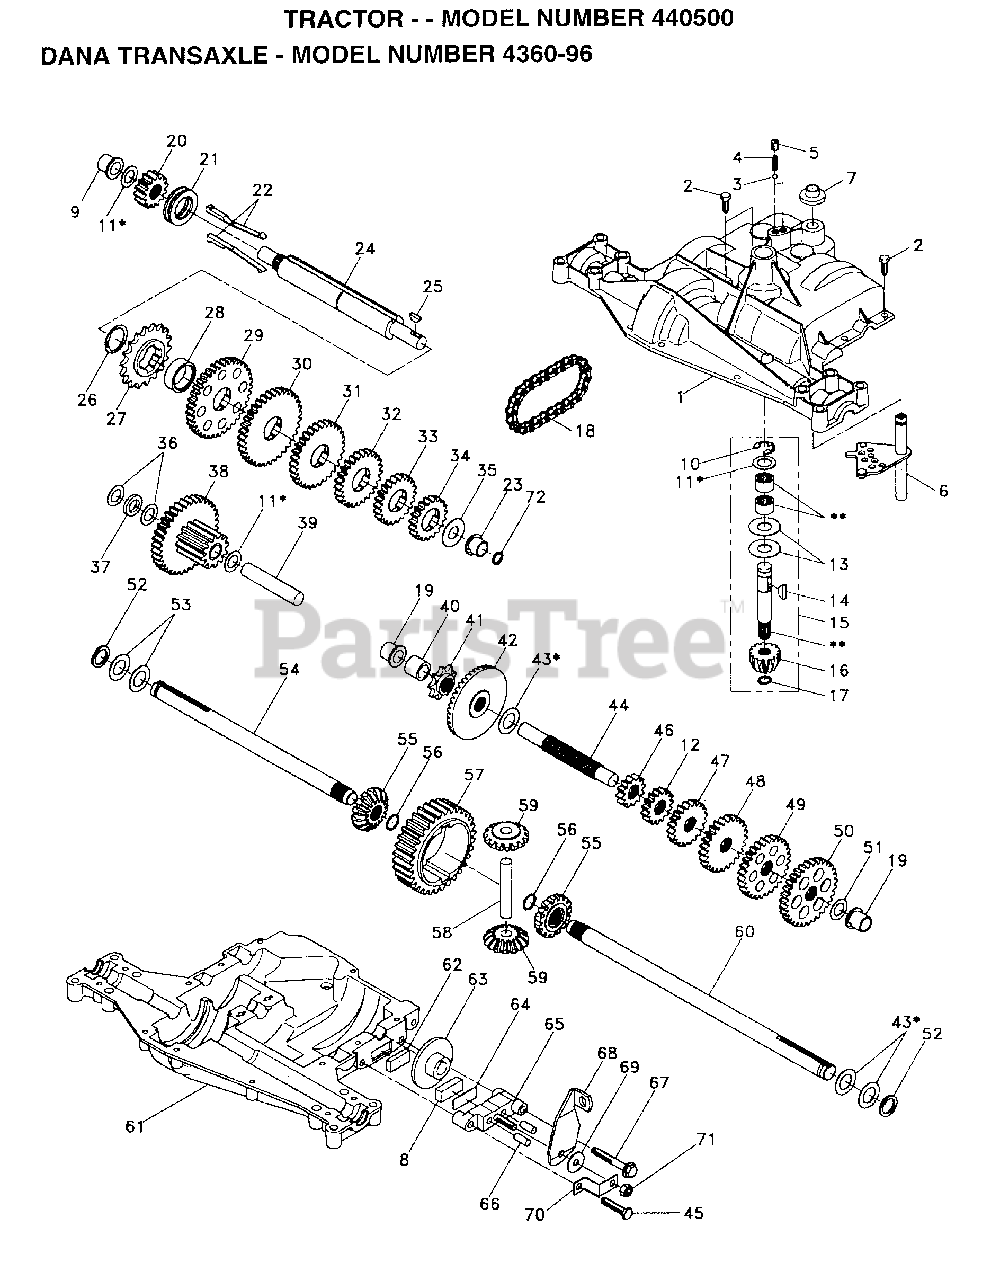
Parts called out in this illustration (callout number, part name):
1	HARNESS.IGNITION
4	"SPRING, DETENT LT"
5	"SCREW, SET LT"
6	KIT SHIFTER ASM
7	SHIFTER BOOT
8	PUCK T
10	RETAINING RING LT
11	ASM KIT SHIM 4689
12	PLUG.PLASTIC
13	WASHER T
14	KEY WOODRUFF-DANA
17	"RING,RETAINING LT"
18	"CHAIN,24 PTCH LT"
19	BEARING.FLNG.5510
20	GEAR SPUR 14 TTH
21	CLUTCH.COL.5467
22	KIT.ASM.CLUTCH KY
23	BEARING.FLNG.5511
24	SHAFT INTERM DANA
25	WOODRUFF KEY
26	"RING,RETAINING LT"
27	SPROCKET 18T T
28	SPACER YT
29	GEAR SPUR 37 TTH
30	GEAR SPUR 35 TTH
31	GEAR SPUR 30T
32	GEAR 25T LT
33	GEAR SPUR 22 TT
34	SPUR GEAR 19T
35	"WASHER, PLAIN LT"
36	WASHER 025
37	SPACER
38	ASSM GEAR COMB
39	SHAFT IDLER
40	SPACER T
41	SPROCKET 9T LT
43	ASM KIT SHIM
44	SHAFT T
45	"SCREW, TAPPING LT"
46	GEAR SPUR 12 TTH
48	"GEAR, SPUR 25T LT"
49	GEAR 28T T
50	"GEAR, SPUR 31T LT"
51	WASHER 060
52	NEOPRENE WASHER
53	WASHER 031
55	GEAR 15T T
56	"RING,RETAINING LT"
58	SHAFT T
59	GEAR 1ST T
61	HOUSING LOWER TNS
62	PUCK T
63	BRAKE DISC. T
64	SPACER LT
66	PIN T
69	WASHER LT
71	NUT.LOCK.5/16-24
72	SEAL.OIL.DAN.5508
